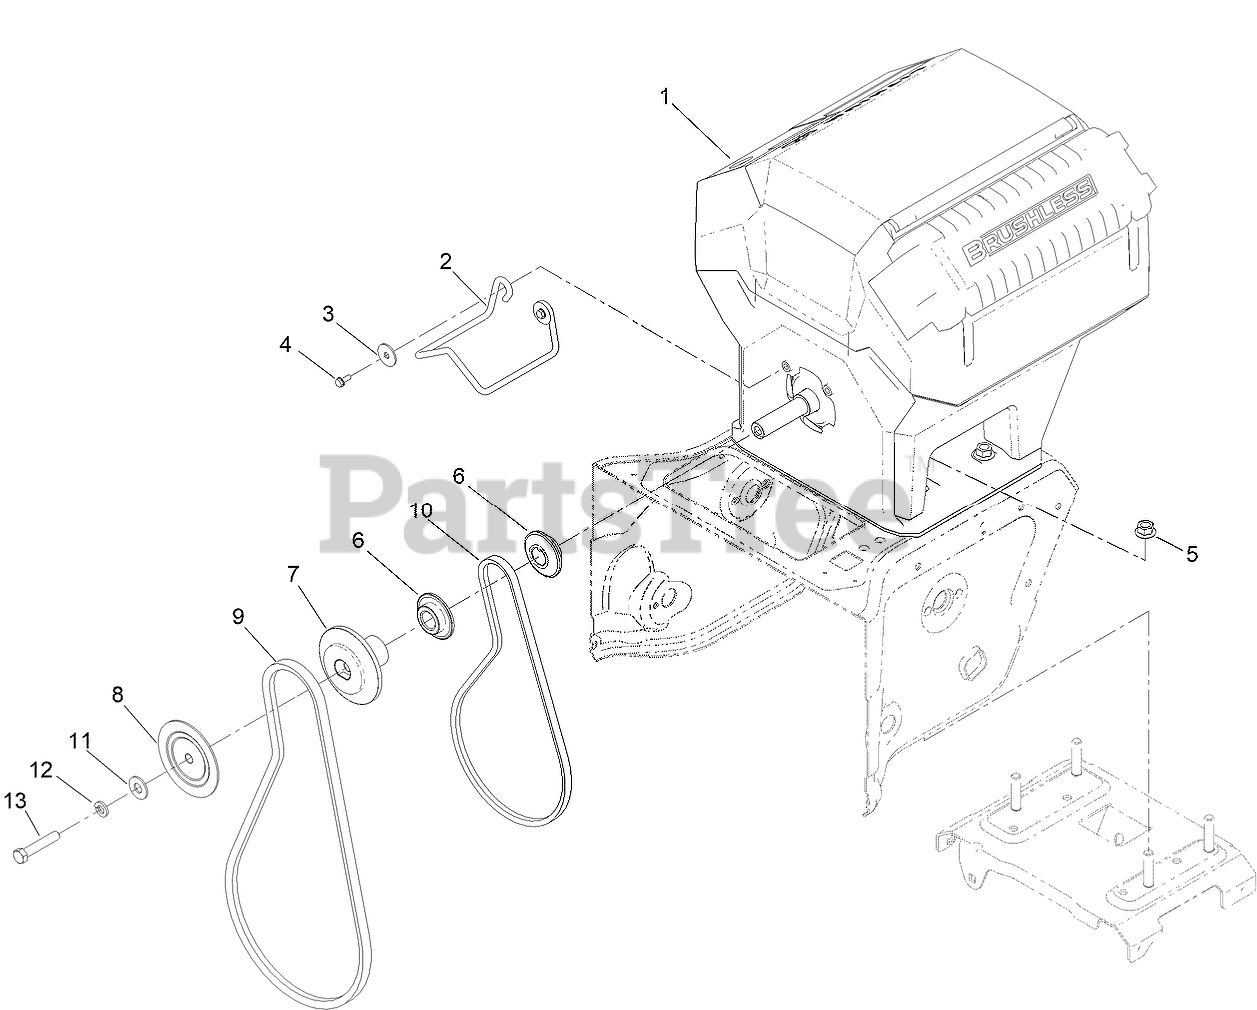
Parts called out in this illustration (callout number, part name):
1	POWERHEAD-60V
2	GUIDE-BELT
3	WASHER-FLAT
4	SCREW-HWH, THD ROLL
5	NUT-LOCK
6	PULLEY-ENGINE, TRACTION
7	PULLEY-AUGER, REAR
8	PULLEY-AUGER, FRONT
9	BELT-V
10	BELT-V
11	WASHER-FLAT
12	WASHER-LOCK
13	SCREW-HH
